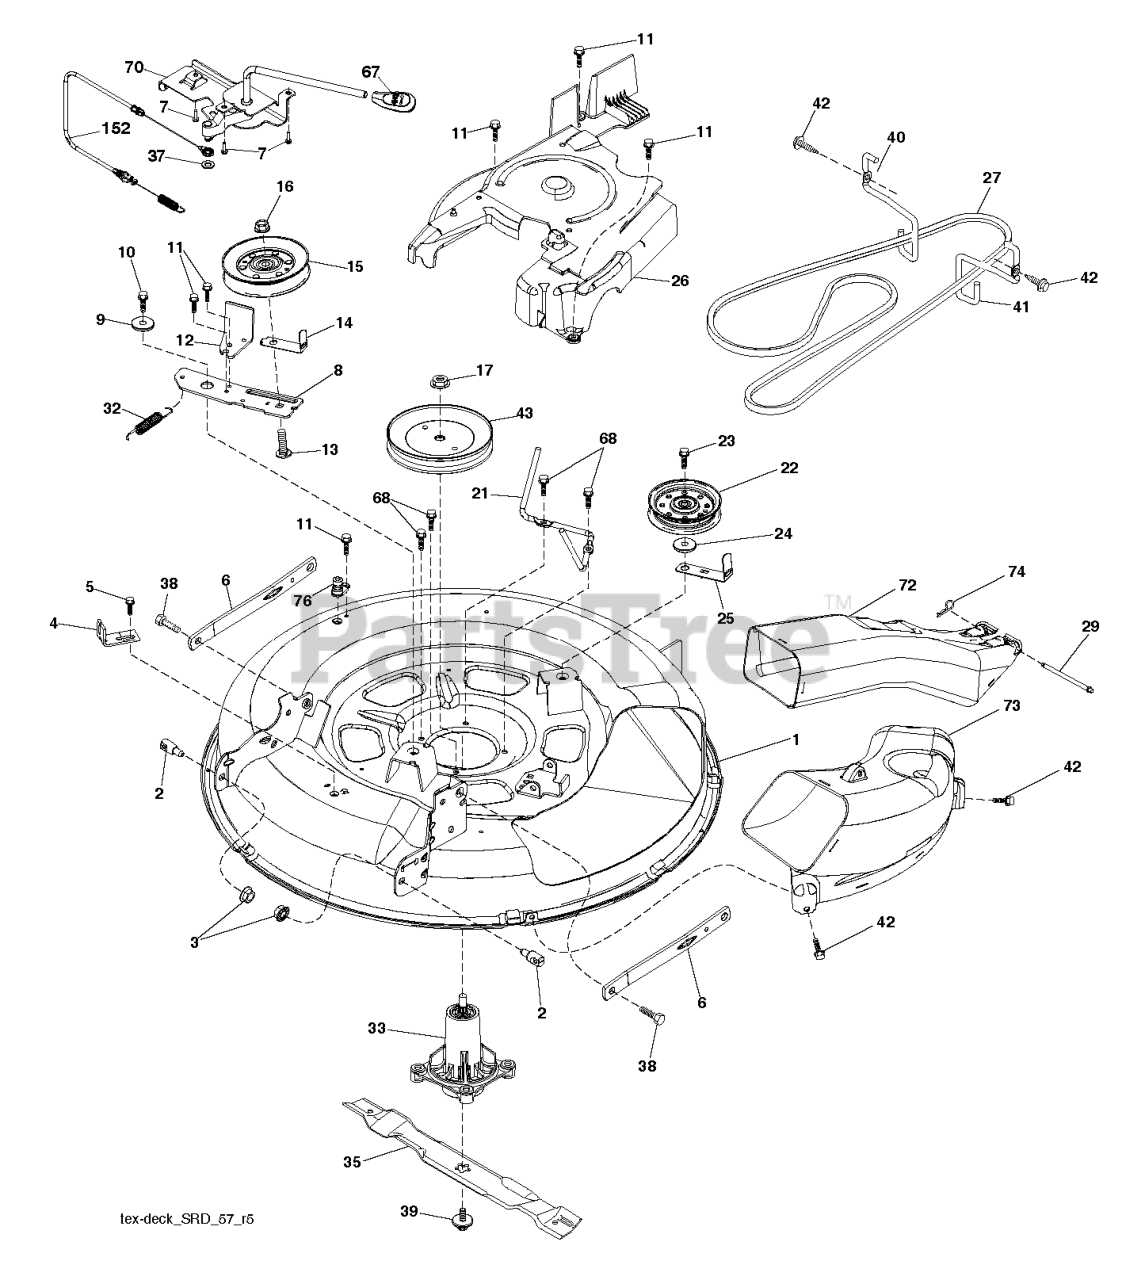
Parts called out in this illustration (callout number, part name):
1	DECK.SVC.WELDMNT.30"419272X418
2	STUD.W/"D"ANTI-ROTATION
4	BRACKET.CLUTCH.CABLE
5	BOLT.5/16HEX.WHS.HD
6	ARMS.SUSP.MOWER.REAR.SRD
8	ARM.IDLER.30"SRD
9	SPACER.RETAINER
10	SCREW 3/8-16X1
11	SCREW.1/4-20X5/8
12	RP ARM.BRAKE.MOWER.38"LH.TEX
13	GSPW Bolts
14	KEEPER, BELT IDLER
15	PULLEY.IDLER.4.25
16	NUT LOCK FLG 3/8-16 UNC
17	NUT.FLANGE.LOCK.TOP
21	KEEPER.BELT.MANDREL.30"
23	BOLT;HEX_3/8-16 X 1.78.CLRZINC
25	KEEPER.BELT.30"SRD
26	COVER.ASM.MANDREL.30"
27	V-BELT.DRIVE.MOWER.30"
32	SPRING RETURN
33	KIT.MANDREL.NONGREASE.TALL
35	BLADE.MOWER.BAGGING.30"
37	WASHER PLAIN WASHER 3/8 X 0.08
38	BOLT.SHOULDER
39	SCREW.SEMS.7/16-20X1.HEX.HEAD
40	KEEPER.BELT.ENGINE.LH.LT.SRD
41	KEEPER.BELT.ENGINE.RH.LT.SRD
42	SCREW, 3/8-16X3/4
43	PULLEY, MANDREL 6.5 PD
67	HANDLE.CLUTCH.CABLE.LT
68	BOLT.HEX.WASHR.HED.313-18X1.19
70	CLUTCH.ASM.MANUAL.LT.PRED
72	CHUTE.UPPER.SRD.30R"
73	CHUTE.LOWER.SRD.30R"
76	PORT.WASHOUT
152	CABLE.CLUTCH.MANUAL.
